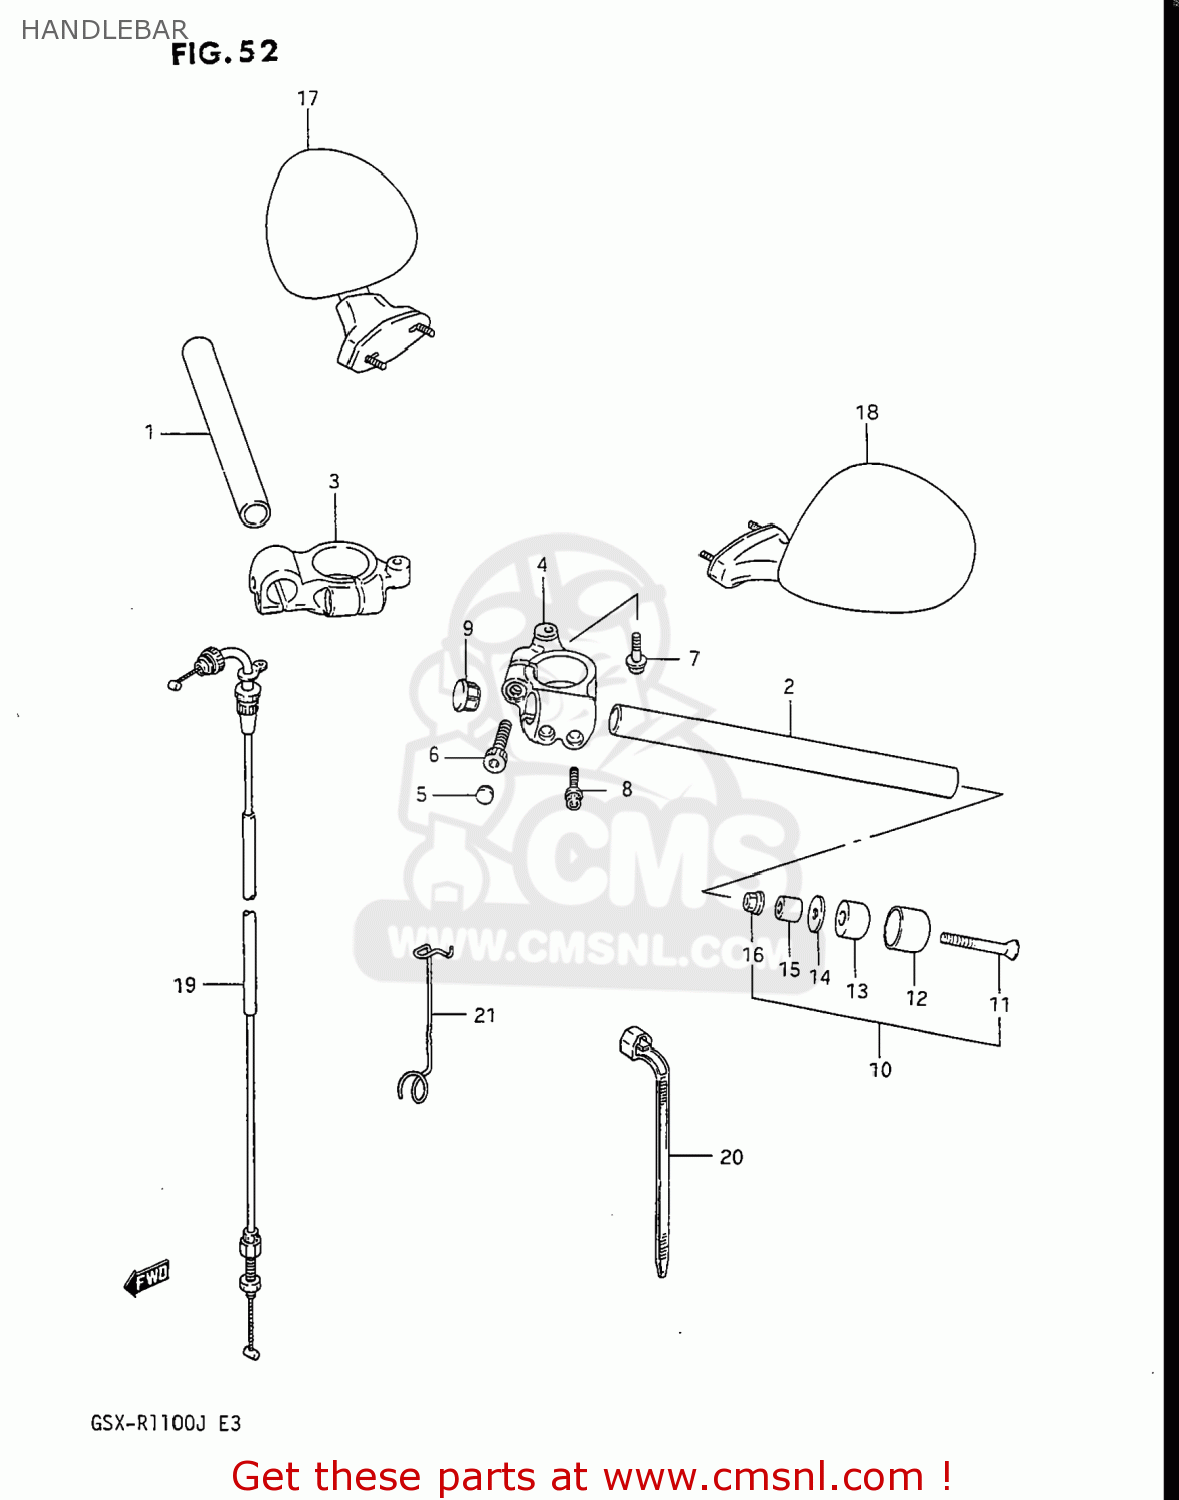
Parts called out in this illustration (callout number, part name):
1	HANDLEBAR,R
2	HANDLEBAR,LEFT
3	HOLDER,HANDLEBAR,RIGHT
4	HOLDER,HANDLEBAR,LEFT
5	CAP(OD:10)
6	BOLT 8X35
7	BOLT
8	BOLT,HANDLEBAR
9	CAP,HANDLEBAR
10	BALANCER SET,HANDLEBAR
11	SCREW
12	CAP,BALANCER
13	BALANCER,HANDLE
14	SPACER,BALANCER
15	EXPANDER,HANDLE BALANCER
16	NUT
17	MIRROR ASSEMBLY,REAR VIEW
18	MIRROR ASSEMBLY,REAR VIEW
19	CABLE ASSY,THROTTLE
20	CLAMP(L:165)
21	GUIDE,SUB T/M CABLE
